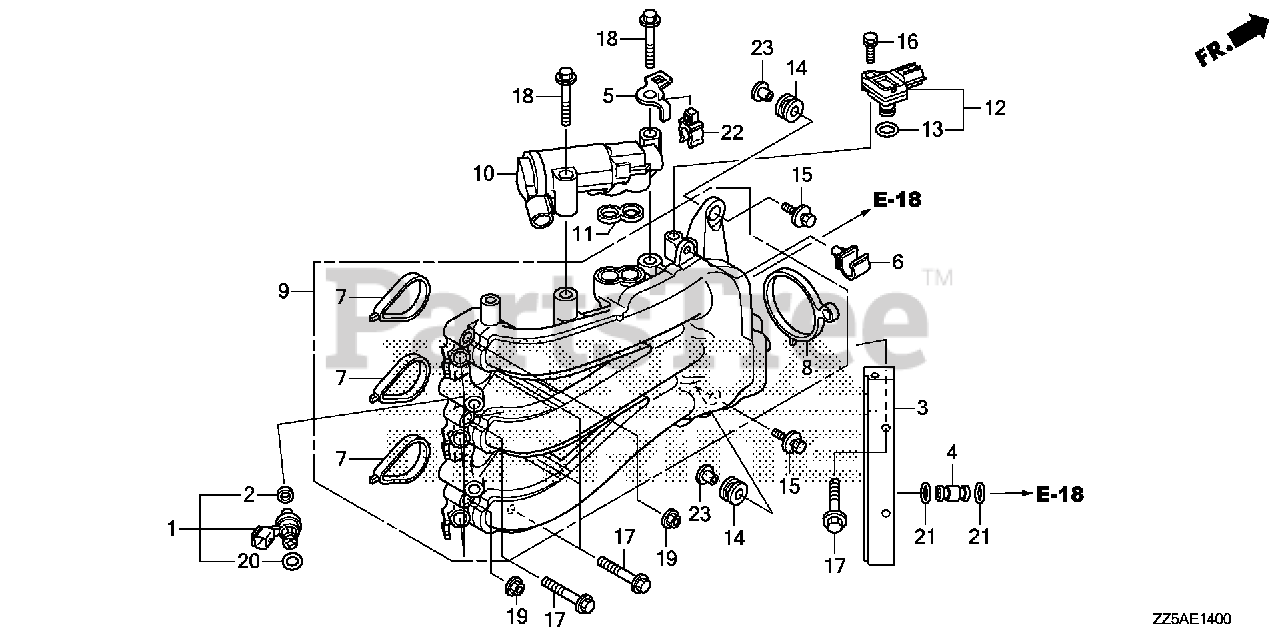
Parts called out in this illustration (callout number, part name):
1	INJECTOR ASSY., FUEL
2	RING, SEAL
3	LINE, FUEL
4	JOINT, FUEL PIPE
5	BRACKET B, TUBE CLAMP
6	CLAMP B, FUEL TUBE
7	GASKET, IN. MANIFOLD
8	GASKET, THROTTLE BODY
9	MANIFOLD, INLET
10	VALVE ASSY., ELECTRONIC AIR CONTROL
11	GASKET, ELECTRONIC AIR CONTROL VALVE
12	SENSOR ASSY., MAP
14	GROMMET, CASE (LOWER)
15	BOLT-WASHER (6X25)
16	BOLT-WASHER (5X18)
17	BOLT, FLANGE (6X32)
18	BOLT, FLANGE (8X45)
19	NUT, FLANGE (6MM)
20	O-RING (7.3X2.2)
21	O-RING (7.8X1.9) (ARAI)
22	CLIP, TUBE (3.5)
23	COLLAR, MODULE IGNITION CONTROL CASE (CDI)
